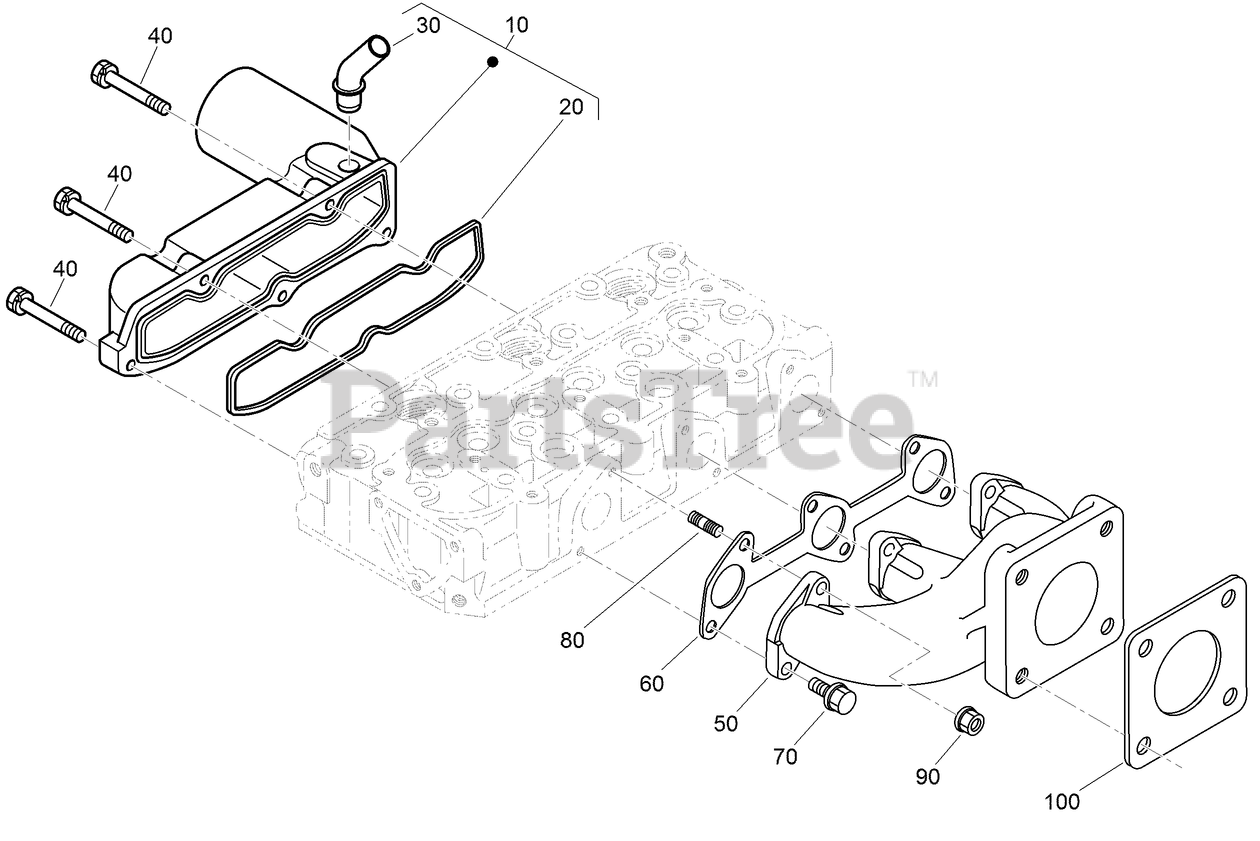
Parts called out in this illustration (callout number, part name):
10	INTAKE MANIFOLD ASM
20	GASKET-MANIFOLD, INTAKE
30	PIPE-BREATHER
50	MANIFOLD-EXHAUST
60	GASKET-MANIFOLD, EXHAUST
70	BOLT-UBS
80	BOLT-STUD
100	GASKET-MUFFLER
